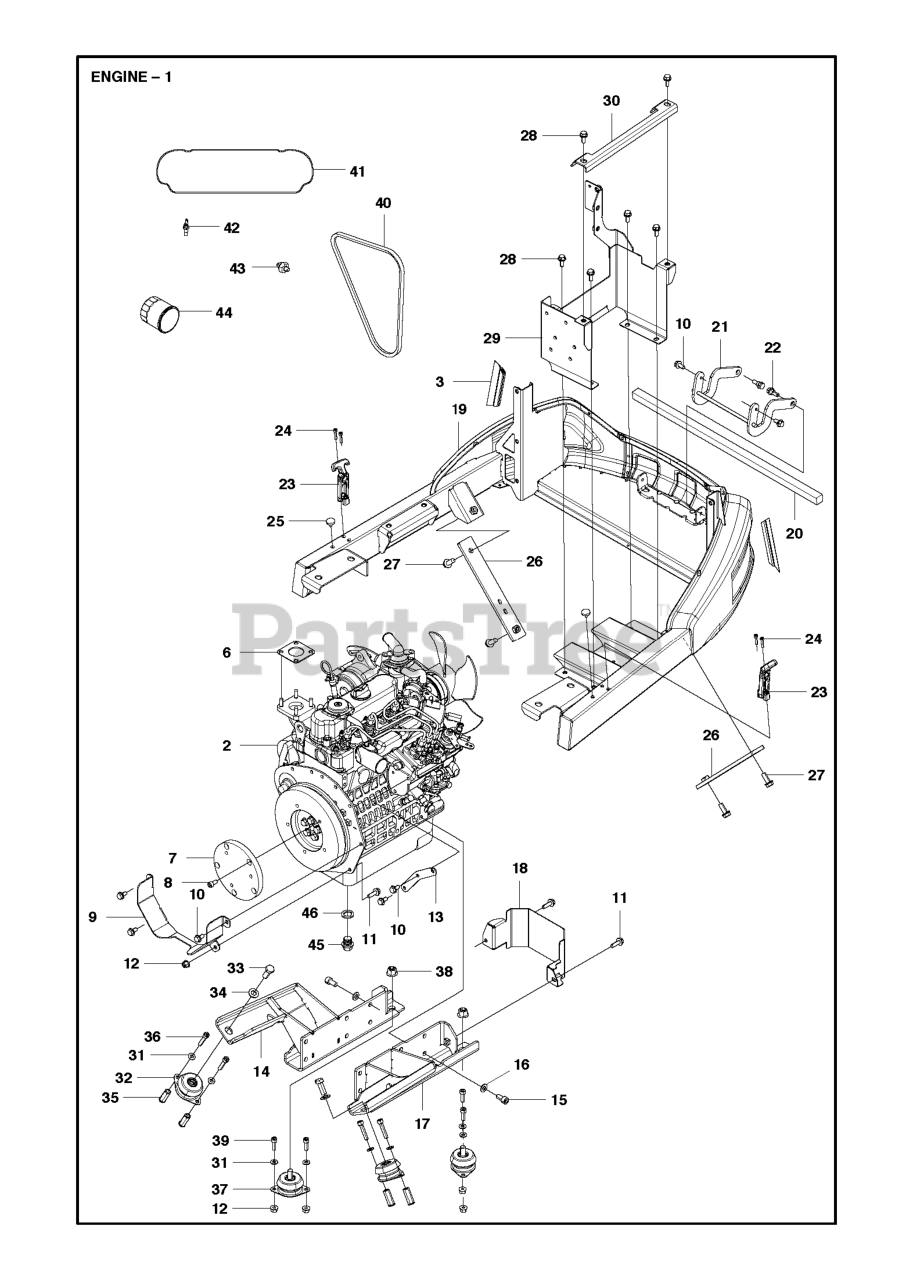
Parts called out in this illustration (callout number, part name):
11	BOLT
12	NUT FLANGE
16	WASHER
24	SCREW IHSCM
31	WASHER BRB 8.4X17
33	Hex Head Capscrew, M12 X 1.75 X 30 DIN933ZP
34	WASHER - M12
